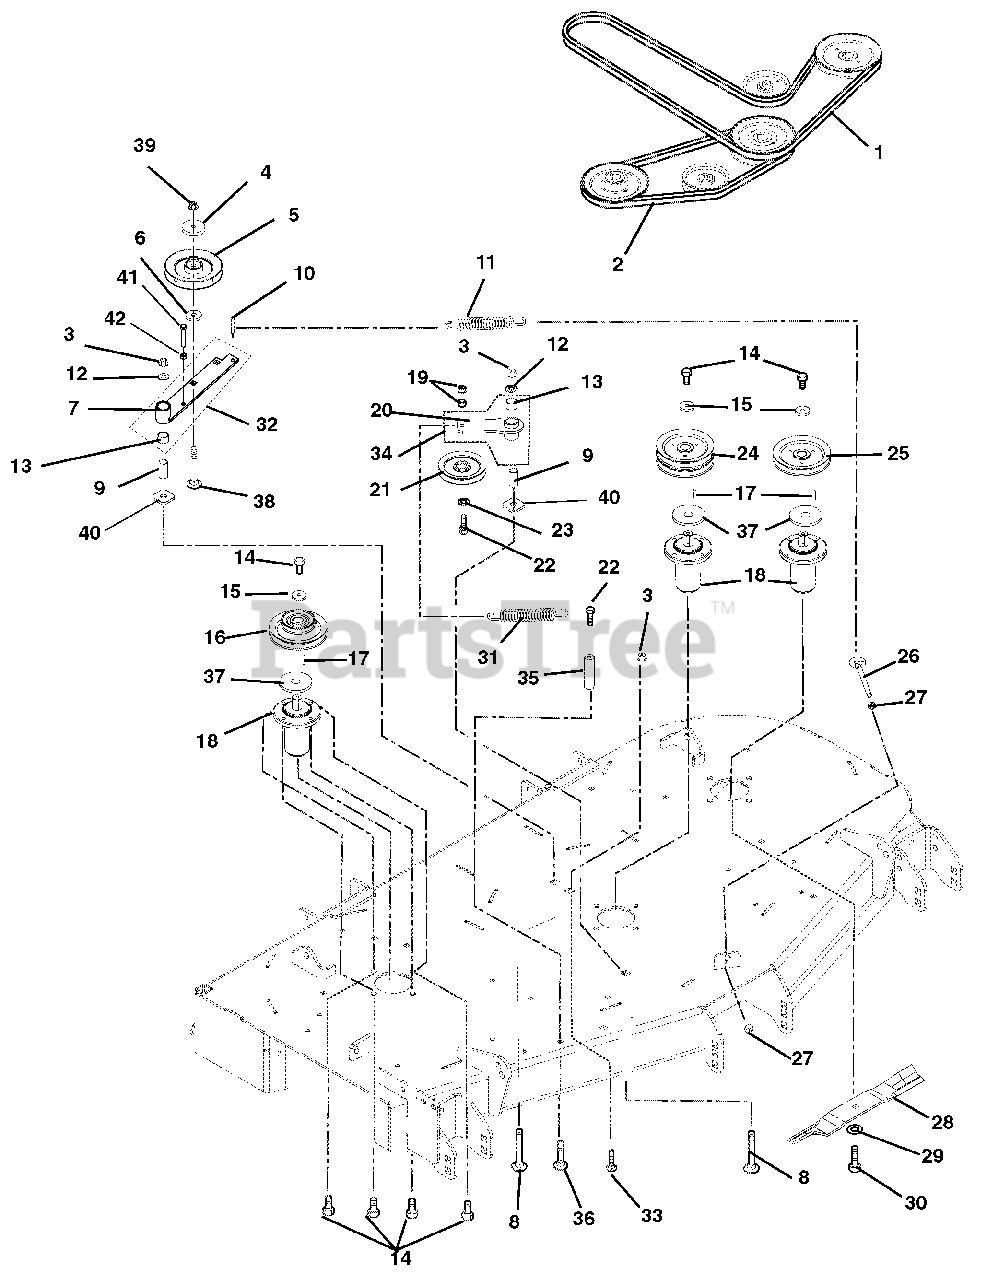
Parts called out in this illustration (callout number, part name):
1	Belt, 184.4" Long, PTO Drive Hex (992156)
2	V-Belt, 63" Long Cog B-Section (992156)
3	Nut, .50-13 Nyloc Flange
4	Cap, Idler Bearing Sealing
5	Pulley, V 6.0 x .500 ID SNGL. Bearing
6	Bushing, Spacer .502 x .997 x .50
7	Idler, Pivot Arm
8	Bolt, Round Head Square Neck .50-13 x 3.50
9	Bushing, Spacer .505/.500 x .999/.996 x 2.05/2.03
10	Bolt, Shoulder EP .38-16 x .30 Hex
11	Spring, Extension (Deck Idler)
12	Washer, Flat Steel .531x 1.250 x.100
13	Bushing, 1.00 x 1.125 x 1.936
14	Bolt, Hex .38-16 x 1.00
15	Washer, Flat Steel .406 x 1.50 x .245
16	Sheave, Double, 1" ID x 6.75" x 4.35" OD (992156)
17	Key, Square .25 x .25 x 1 RC 40-50
18	Spindle Assembly
19	Nut, Locking-Center .38-16
20	Idler, Pivot Arm
21	Assembly, V-Idler 5.00 O.D.
22	Bolt, Hex .38-16 x 2.25
23	Washer, Flat Steel .406 x .812 x .065
24	Sheave, Double 1" ID x 6.75" OD (992156)
25	Sheave, Single 1" ID x 6.75" OD (992156)
26	Bolt, .38-16 x 4.50 .62 Diameter Eye
27	Nut, Hex, Jam .375-16
28	Blade, Mower (20.50") (992156)
29	Washer, Bellville .63 x 1.625 x.14
30	Bolt, Hex .62-18 x 1.75 Grade 8
31	Spring, Extension
32	Assembly, PTO Idler Pivot Arm (Includes item # 7 and item # 13)
33	Bolt, Round Head Square Neck .50-13 x 1.5, Full Thread, Grade 5
34	Assembly, Idler Pivot Arm (Includes item # 13 and item # 20 )
35	Nut, Coupling .375-16 x 1.75
36	Bolt, Round Head Square Neck .38-16 x 1.00
37	Retainer, Grease
38	Bolt, Round Head Square Neck .50-13 x 3.00 Grade 5
39	Nut, Nyloc Flange .50-13
40	Washer, Flat .640 x 1.75 x .250
41	Bolt, Hex .38-16 x 2.75 Grade 5
42	Nut, Hex .38-16
